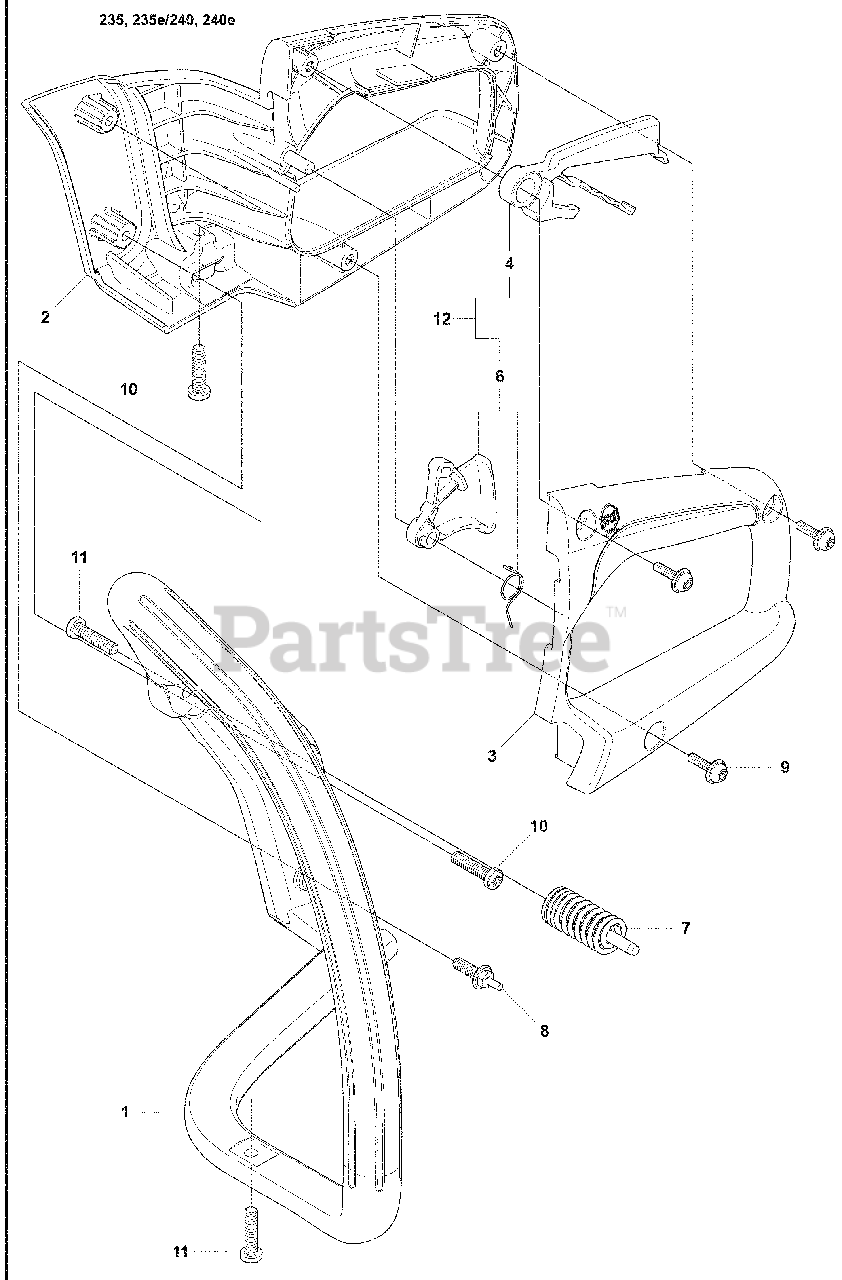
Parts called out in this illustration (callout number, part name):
1	FRONT HANDLE
2	REAR HANDLE W/OVMLD 240e
2	REAR HANDLE 235/235e
3	REAR HANDLE COVER W/OVMLD 240e
3	REAR HANDLE COVER 235/235e
4	LOCKOUT- THROTTLE
6	ASSY TRIGGER & SPRING
7	ASS'Y FRONT ISOLATOR
8	ISOLATION LIMITER SCREW
9	SCREW 8-16X15.1 PL PAN.TRX
10	SCREW M5.28X1.81X16MM PLAS
11	SREW M5.38-14X22.225MM
12	KIT TRIGGER & LOCKOUT
